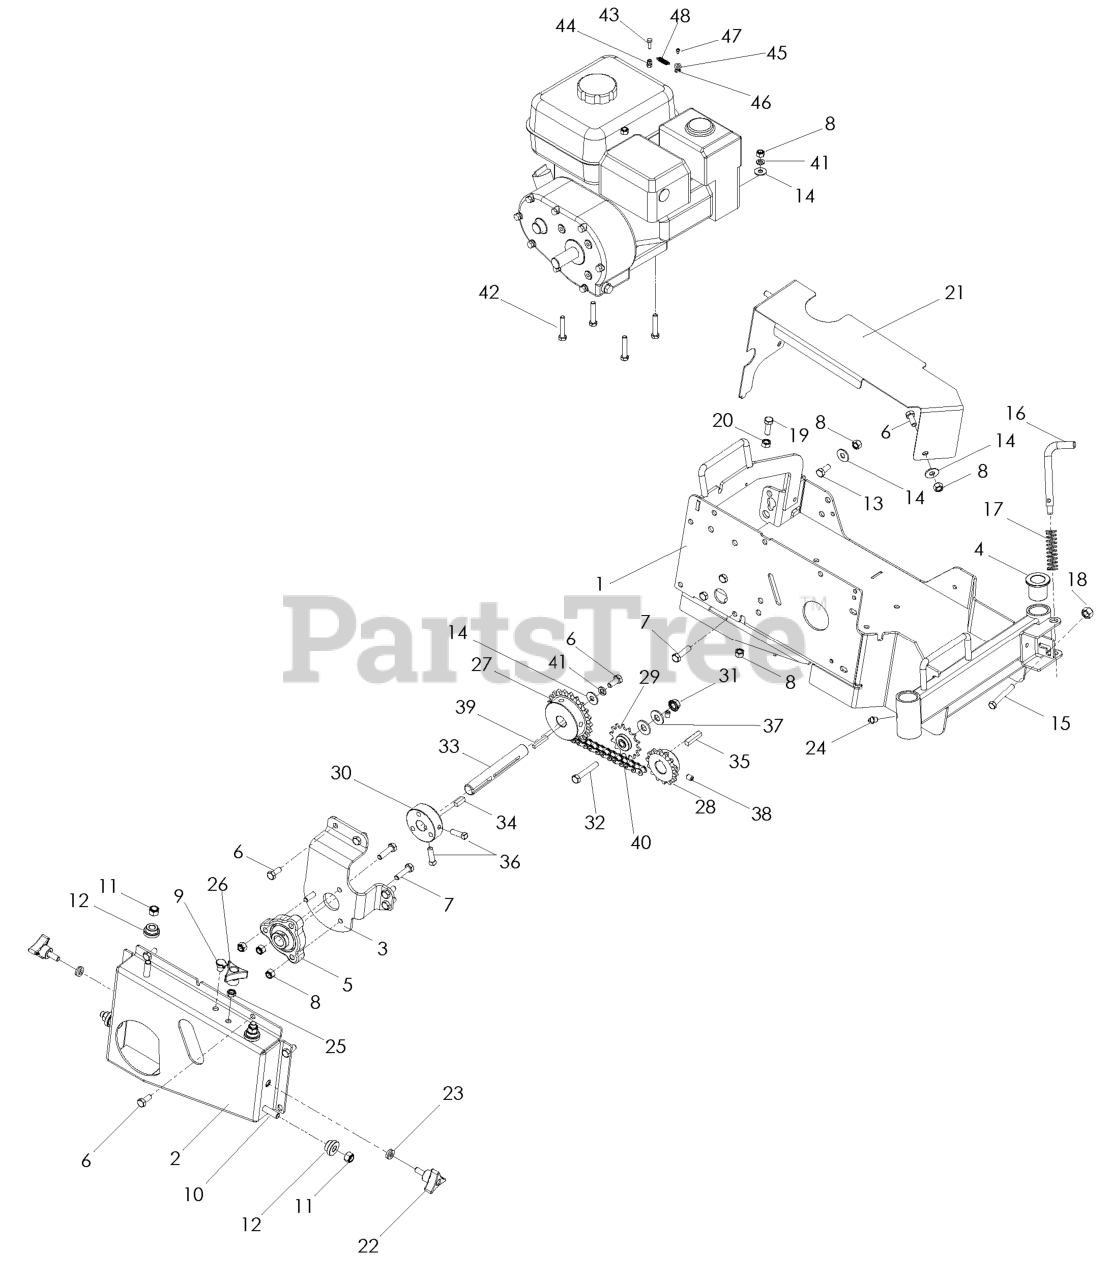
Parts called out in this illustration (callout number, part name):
1	FRAME WELDMENT, ORANGE
2	CHAIN COVER, ORANGE
3	BEARING SUPPORT, ORANGE
4	BUSHING, FLANGED
5	BEARING, FLANGED
6	HCS 5/16C X 3/4
7	HCS 5/16C X 1 1/4
8	NUT 5/16 NYLOC
9	OIL CAP, 3/8"
10	HCS 3/8C X 1 1/4 GR5
11	NUT 3/8-16 NYLOC
12	BUSHING RAKE
13	SCREW 5/16C X 1 HEX CAP
14	WASHER 5/16 FLAT
15	BOLT 1/4C X 1 3/4
16	SPRING PIN
17	SPRING, COMPRESSION
18	NUT.1/4-20.HEX.NYLOC.ZD
19	HCS 5/16C X 1
20	NUT 5/16C HEX
21	COVER, ORANGE
22	KNOB W/STUD
24	ZERK 1/8 NPT
25	NUT 5/16-18 HEX JAM ZD
26	KNOB, 5/16-18 NYLOC
27	SPROCKET, 21T W/SETSCREWS
28	SPROCKET, ENGINE
29	SPROCKET W/KEY JACK SHAFT 10 T
30	MOUNTING HUB
31	NUT 3/8C WHIZ
32	HCS 3/8-16 X 1 3/4 GR5
34	KEY 1/4 SQ X 3/4
35	KEY 7MM SQ X 33MM ENGINE
36	SCREW 5/16C X 1 SQ HEAD SET
37	WASHER 3/8 FLAT
38	SET SCREW 5/16 NYLOC
39	KEY 3/16 SQ X 1-1/4
40	CHAIN, TRANSMISSION #40
41	WASHER.LOCK.HVY.HLCL.SPR.5/16
42	HCS 5/16C X 1 3/4
43	HCS M5-0.8 X 16MM GR 8.8 ZD
44	NUT 5MM-.8 HEX ZD
45	CLAMP, THROTTLE CABLE
46	CLIP, THROTTLE HONDA
47	SCREW METRIC SPECIAL X 1/4 ZN
48	SPRING, THROTTLE, HONDA ENGINE
